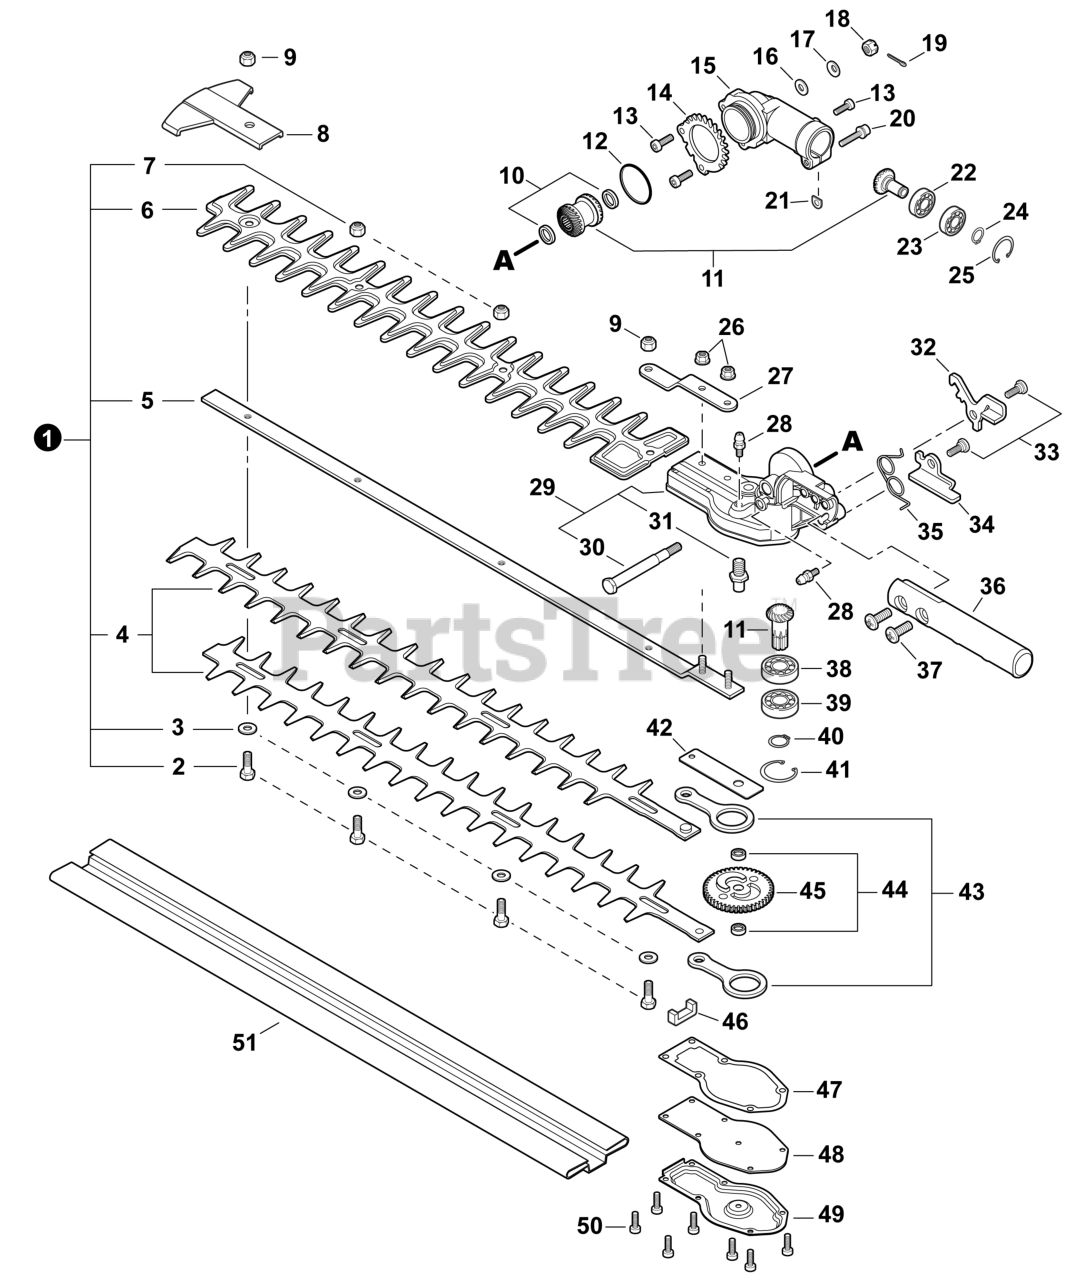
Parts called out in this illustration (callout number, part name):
1	CUTTER ASSY, 22"
2	BOLT M6×20
3	WASHER M6
4	CUTTER 22"
5	GUIDE BAR 22"
6	GUARD, CUTTER BLADE
8	GUARD, TIP
10	COLLAR Ø16ר10×L= 2
11	GEAR SET
13	BOLT 5×12
14	RING, LOCKING
15	HOUSING, UPPER GEAR CASE
16	WASHER 6.5×13×1
17	WASHER, CONE M6
19	PIN, COTTER Ø1.6×15
20	BOLT M5×25
21	D-WASHER
22	BEARING, BALL 609
23	BEARING, BALL 609ZZ
24	RING, SNAP Ø9
25	RING, SNAP 24
26	NUT, FLANGE M5
27	BRACKET, CUTTER
28	FITTING, GREASE
29	GEAR CASE HOUSING ASSY
31	MAINSHAFT
32	LEVER, LOCK
33	BOLT M6
34	RELEASE, LOCK
35	SPRING, TORSION
36	LEVER, ADJUSTMENT
37	SCREW, TRUSS M6×20
38	BEARING, BALL 6001
39	BEARING, BALL 6001ZZ
40	RING, SNAP Ø12
41	RING, SNAP 28
42	PLATE, GUIDE
44	SPACER Ø11ר8×3.4
45	GEAR, CAM
46	PACKING, FELT
47	GASKET, GEAR CASE
49	COVER, GEAR CASE
50	BOLT 4×10
51	SCABBARD
